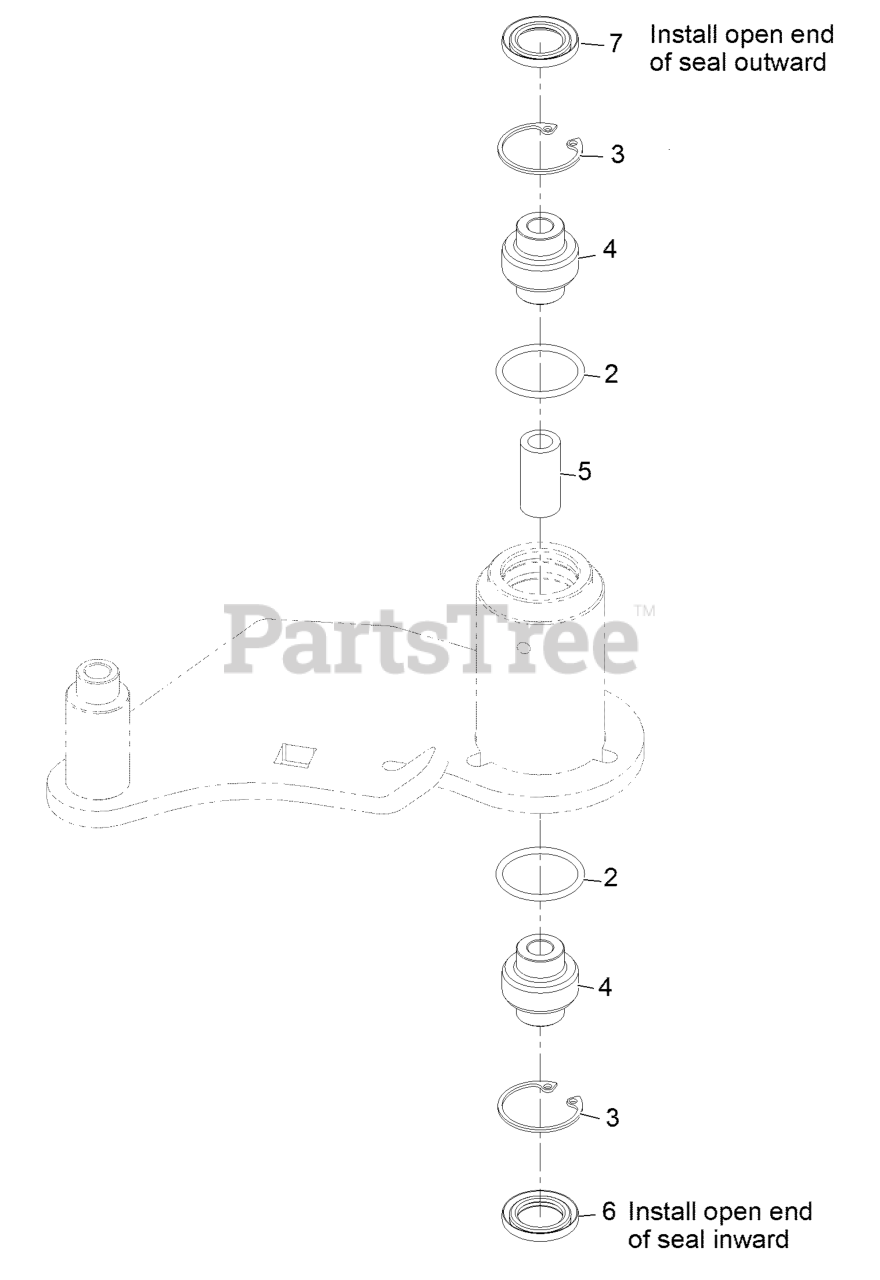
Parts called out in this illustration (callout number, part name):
3	RING-SNAP
4	BEARING-SPHERICAL
6	SEAL-LIP, DOUBLE
7	SEAL-LIP, SINGLE
